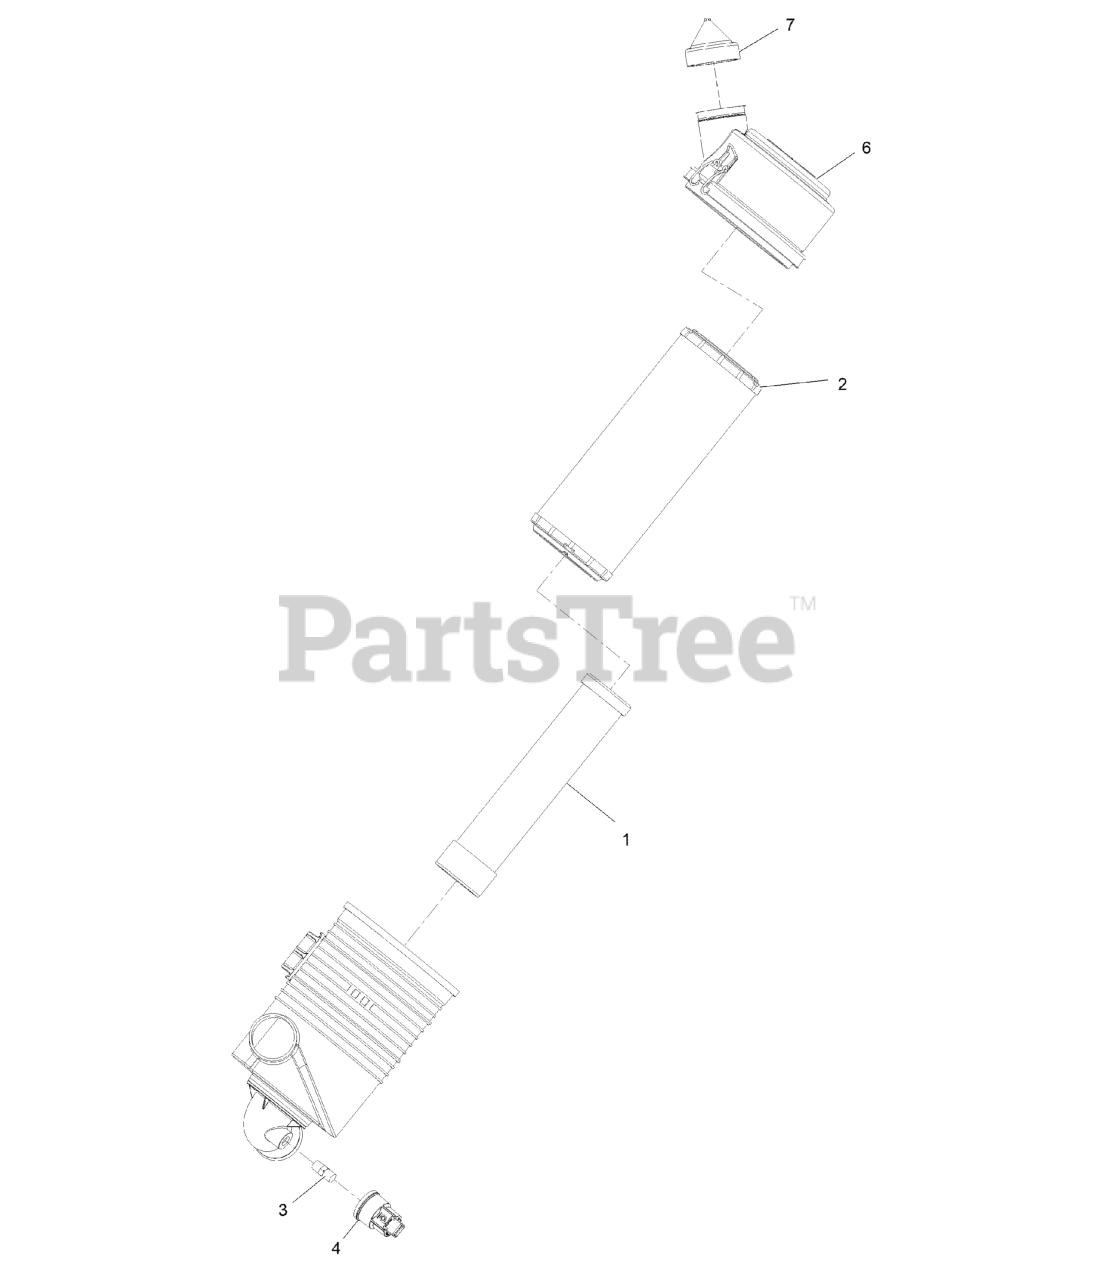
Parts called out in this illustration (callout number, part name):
1	FILTER-AIR, SAFETY
3	ADAPTER-INDICATOR
4	INDICATOR-MINI
6	COVER ASM
7	Valve-Dust-Air Cleaner
